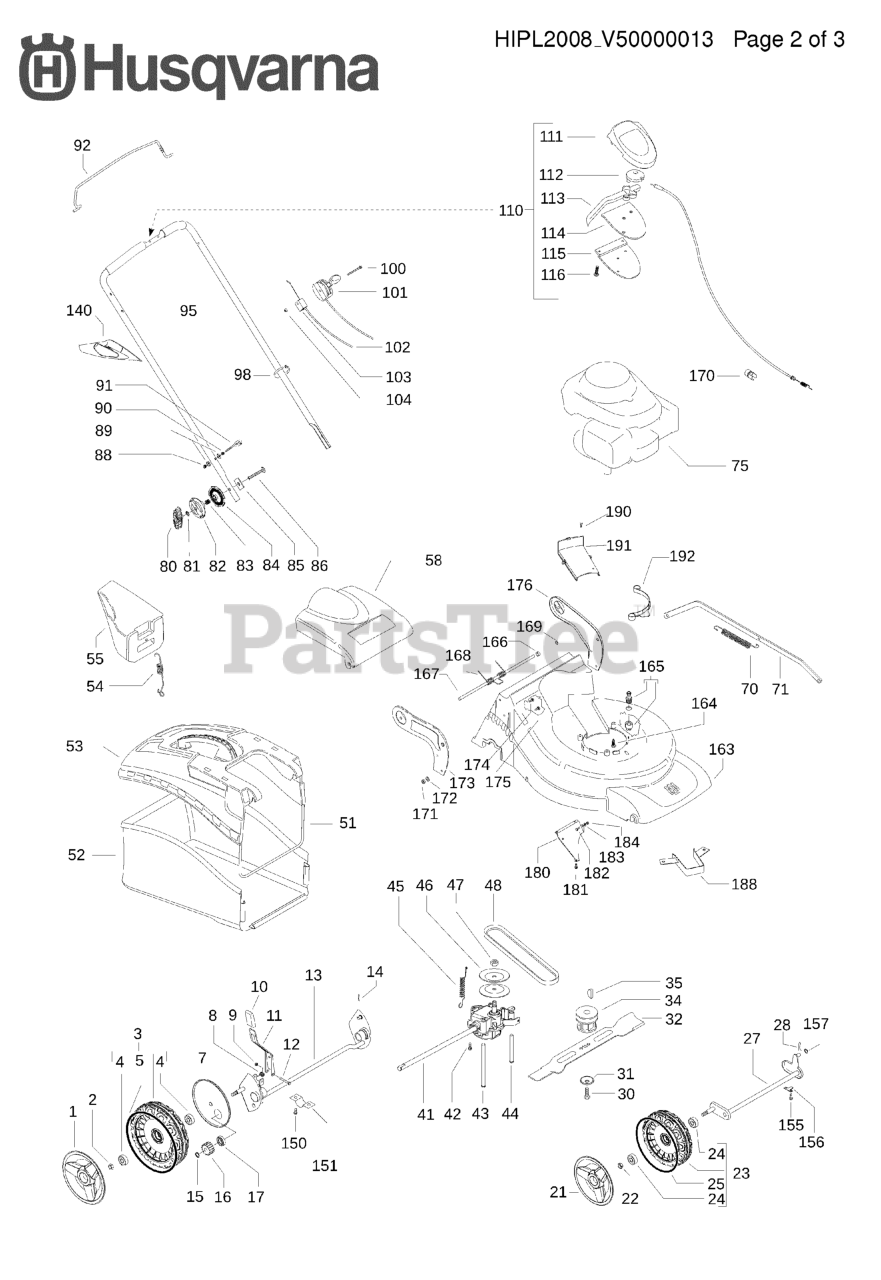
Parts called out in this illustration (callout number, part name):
11	LIFTING LEVER ASSY FOR REAR AX
51	FRAME 51 CAST
53	COVER HARD TOP
58	DEFLECTOR 51 CAST ORANGE
102	BRAKE WIRE
111	CASE.TOP.GRAY
112	PULLEY.CAM.DRIVE.CONTROL.HV
113	LEVER
114	CASE BOTTOM
115	BRACKET, DRIVE CONTROL
116	SCREW, PHILLIPS HEAD 10 X 5/8
168	SPRING 51 CAST
